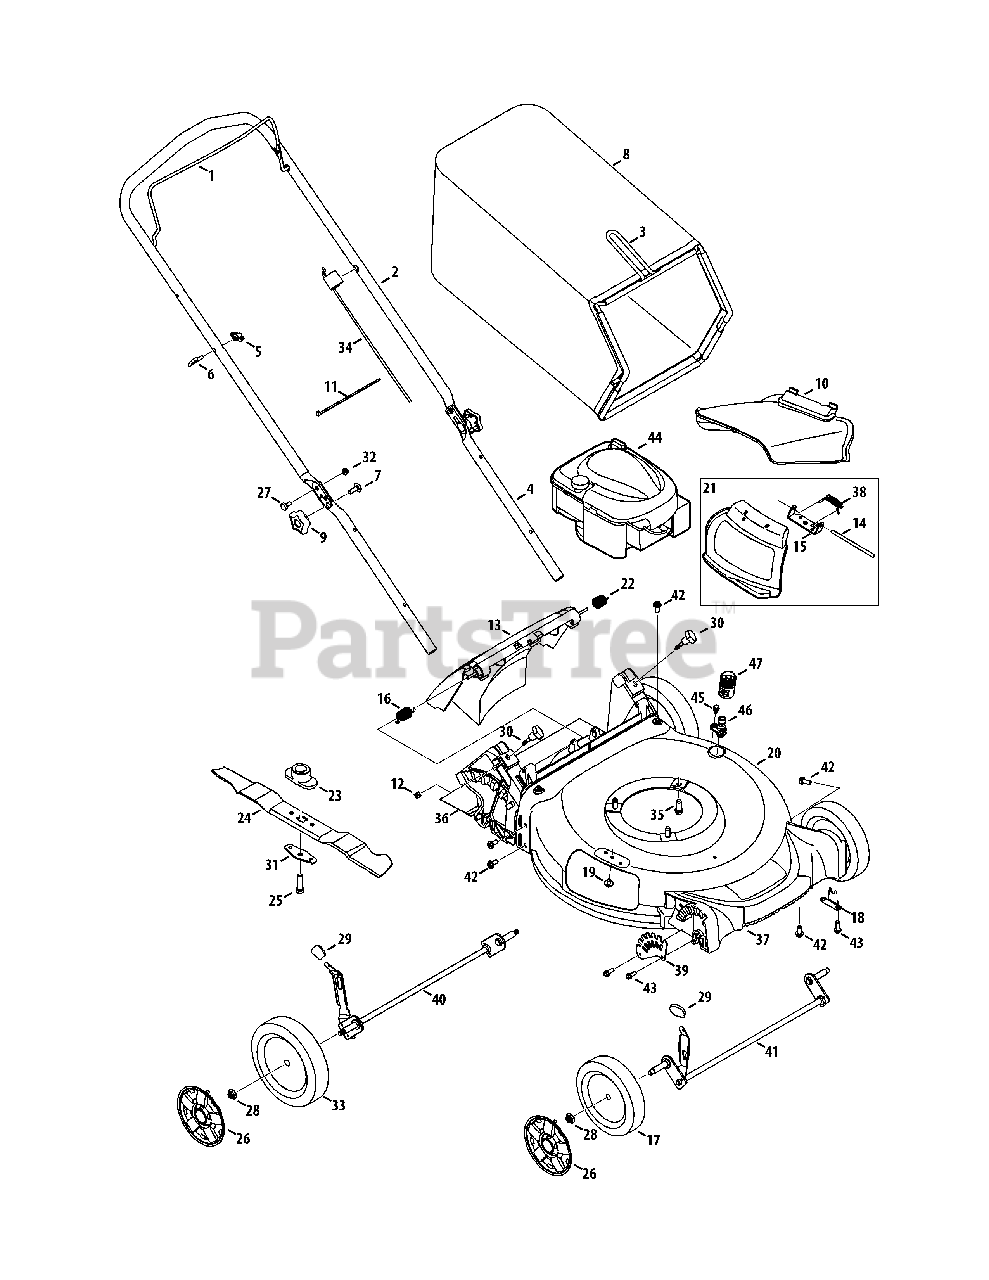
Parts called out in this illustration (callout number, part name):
1	Blade Control
2	Upper Handle
3	Grass Catcher Frame-Black
4	Lower Handle
5	Wing Nut
6	Rope Guide
7	Carriage Screw ,5/16-18
8	Grass Bag
9	Hand Knob
10	Side Chute
11	Cable Tie
12	Nut, Sq., 1/4-20
13	Rear Discharge Door Assembly
14	Hinge Pin
15	Chute Deflector Bracket
16	Torsion Spring - RH
17	Wheel, 7 x 2
18	Axle Retainer Bracket
19	Screw, 1/4-20 x .500
20	Deck - 21"
21	Hinged Mulch Plug Assembly
22	Torsion Spring - LH
23	Blade Adapter
24	Mulching Blade
25	Screw , 3/8-24 x 1.50
26	Hub Cap - Front
27	Sldr. Screw, .375 x .126 x 1/4-20
28	Flange Lock Nut, 3/8-16
29	Adjustment Lever Knob
30	Wing Nut
31	Blade Bell Support
32	Nut, Flange Lock, 1/4-20
33	Wheel, 8 x 2.125
34	Control Cable
35	TT Sems Screw, 3/8-16 x 1.0
36	Trail shield
37	Front Cover
38	Torsion Spring
39	Front Height Adjuster Plate
40	Rear Axle Assembly
41	Front Axle Assembly
42	Screw, 5/16-14 x .750
43	Screw, 1/4-15 x .750
44	Engine - 128T02-0866-B1
45	Screw, 1/4-20 x .500
46	Deck Wash Nozzle
47	Water Nozzle Adapter
